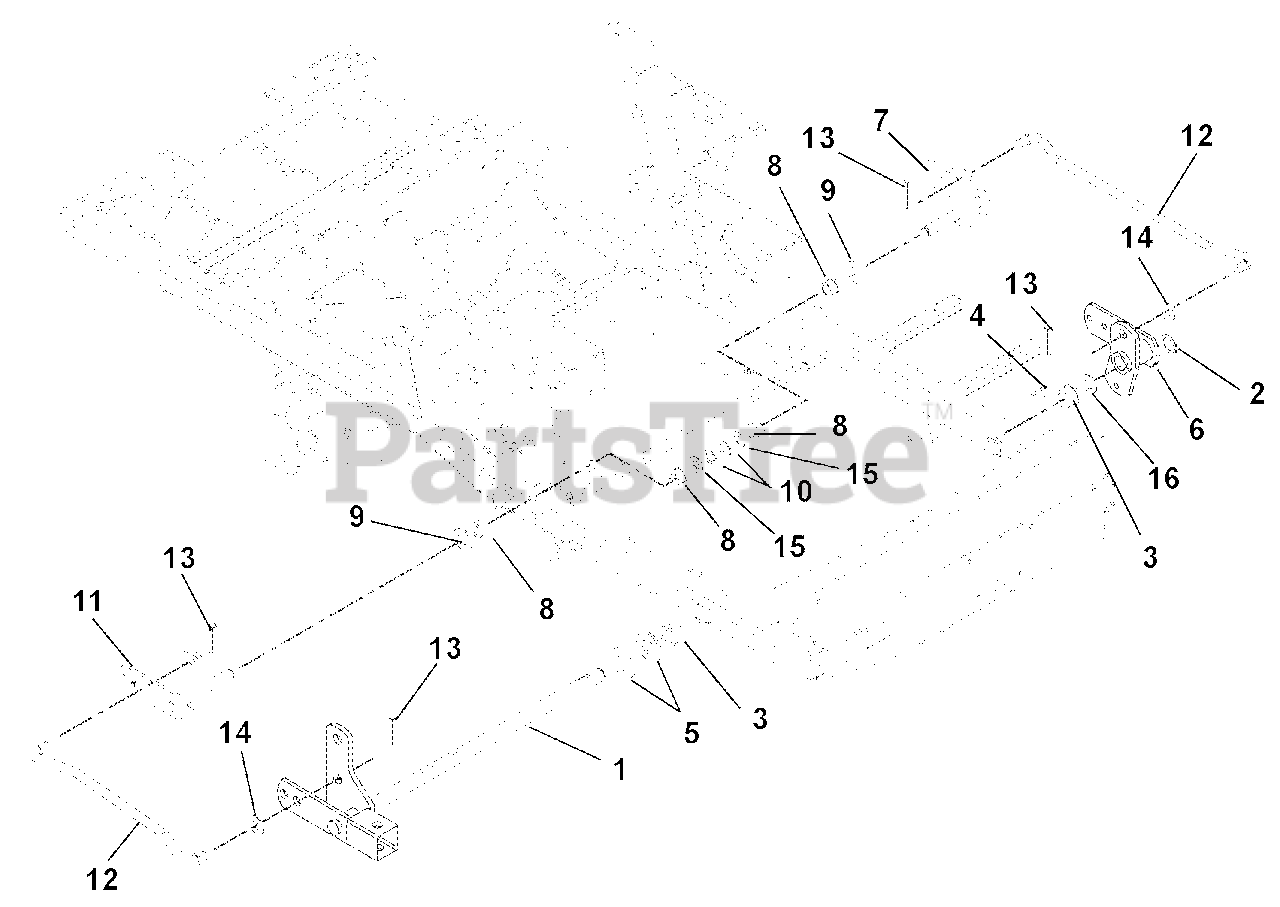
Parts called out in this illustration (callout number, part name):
1	Lift, Mower
2	Ring, Retaining External 1.00 x .078
3	Bushing, Flange 1.00 x 1.12 x .75 x 1.375
4	Key, Woodruff .25 x 1.00
5	Washer, Flat Steel 1.062 x 2.00 x .134
6	Weldment, Lift Arm – Front
7	Weldment, Rear Lift Arm – Left Hand
8	Bushing, Flange Nylon .762 x 1.0 x .58 x 1.48
9	Washer, Hardened Steel .758 x 1.23 x .031
10	Ring, Retaining, External .689 x .077
11	Weldment, Rear Lift Arm – Right Hand
12	Rod, Lift Assist 19.35"
13	Pin, Roll .25 x 1.25 Stainless Steel
14	Washer, Flat Steel .630 x 1.25 x .062
15	Washer, Flat Steel .812 x 1.50 x .135
16	Washer, Hardened Thrust 1.00 x 1.55 x .03
